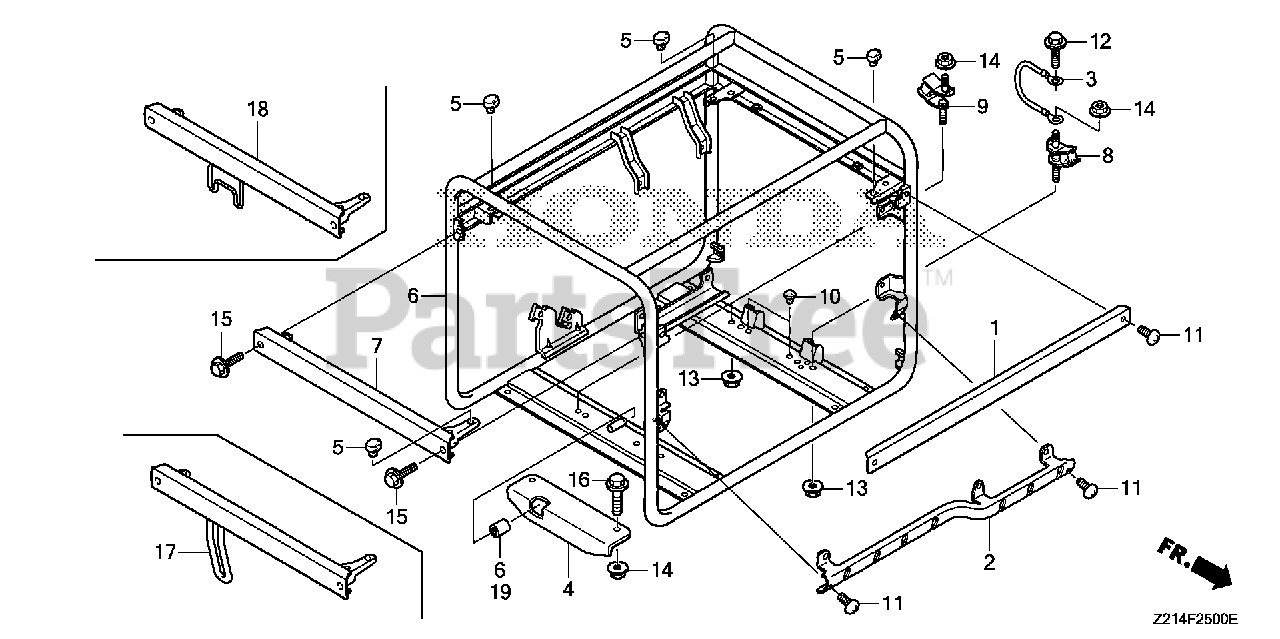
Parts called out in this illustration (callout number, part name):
1	GUARD, CONTROL PANEL (UPPER) *NH105* (MAT BLACK)
2	GUARD, CONTROL PANEL (LOWER) *NH105* (MAT BLACK)
3	CABLE, SUB-GROUND
4	BRACKET, STOPPER
5	RUBBER, FUEL TANK MOUNTING
6	FRAME *NH105* (EM) (MAT BLACK)
7	FRAME, SIDE *NH105* (MAT BLACK)
8	RUBBER (LOWER)
9	RUBBER (LOWER)
10	RUBBER, BUMP STOP
11	SCREW, TRUSS (6X12)
12	BOLT, GROUND (6X16) (WASHER 12.5MM) (ZN)
13	NUT, FLANGE (8MM)
14	NUT, FLANGE (10MM)
15	BOLT, FLANGE (8X16)
16	BOLT, FLANGE (10X40)
